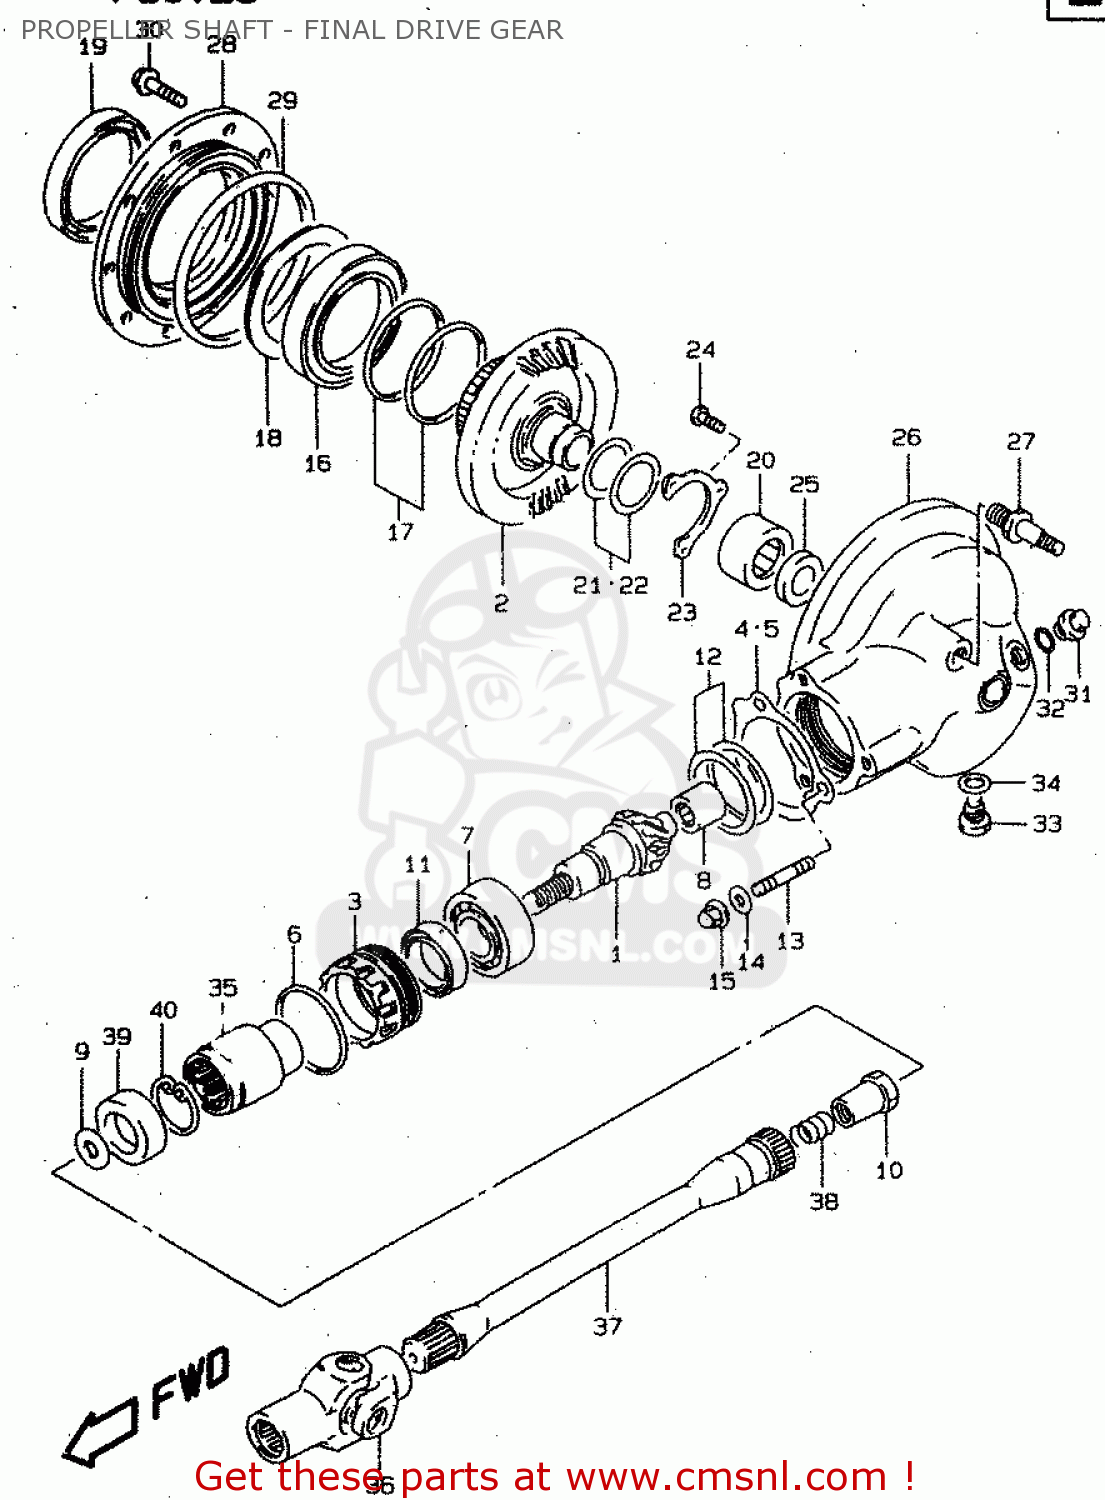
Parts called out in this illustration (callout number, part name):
1	GEAR,FINAL DRIVE BEVEL(NT:11)
2	GEAR,FINAL DRIVEN BEVEL(NT:34)
3	STOPPER,FINAL DRIVE BEARING
4	PLATE,BEARING STOPPER
5	PLATE,BEARING STOPPER
6	O RING(D:1.9,ID:61.6)
7	BEARING(30X62X23.8)
8	BEARING(17X32X16)
9	WASHER(16X29X4)
10	NUT
11	SEAL,OIL(38X54X6)
12	SHIM SET,FINAL DRIVE GEAR
13	BOLT,STUD
14	WASHER
15	NUT
16	BEARING(70X110X13)
17	SHIM SET,DRIVEN GEAR BEARING
18	PLATE,FINAL DRIVEN BRG OIL
19	SEAL,OIL(70X96X16)
20	BEARING(32X46X17.7)
21	SHIM SET,FINAL DRIVEN GEAR
22	SHIM SET,FINAL DRIVE GEAR
23	RETAINER,FINAL DRIVEN GEAR BRG
24	SCREW
25	SEAL,OIL(30X42X7)
26	CASE,FINAL
27	BOLT,STUD
28	CASE,FINAL GEAR BEARING
29	O RING(D:3.5,ID:131.6)
30	BOLT
31	PLUG
32	O RING(D:2.4,ID:17.8)
33	PLUG
34	GASKET(13.8X18.8X4.8) (NAS)
35	COUPLING,FINAL DRIVE GEAR
36	YOKE COMP,UNIVERSAL JOINT
37	SHAFT,PROPELLER
38	SPRING
39	SEAL,OIL(28.4X48X15)
40	CIRCLIP
